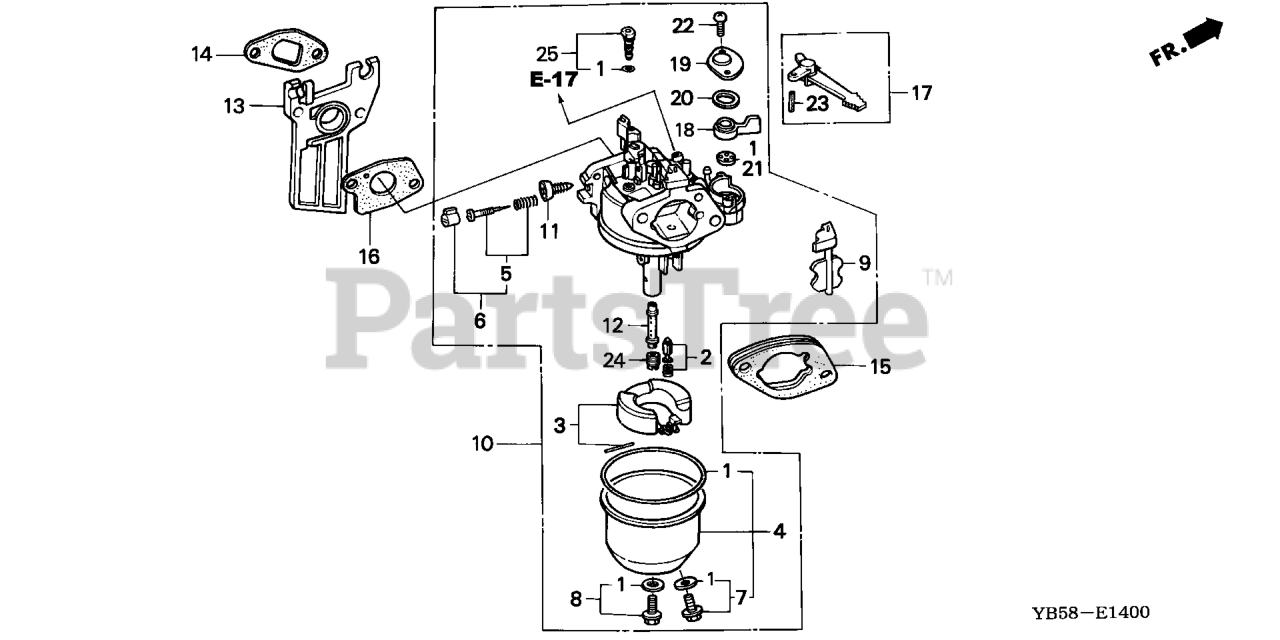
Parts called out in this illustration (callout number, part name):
1	GASKET SET (CARBURETOR NO.)
2	VALVE SET, FLOAT (CARBURETOR NO.) (SEAT NOT INCLUDED)
3	FLOAT SET
4	CHAMBER SET, FLOAT (CARBURETOR NO.)
6	SCREW SET (Honda Code 4219879). (CARBURETOR NO.)
7	SCREW SET, DRAIN (Honda Code 1672187). (CARBURETOR NO.)
8	SCREW SET B
8	SCREW SET
9	CHOKE SET
10	CARBURETOR ASSY. (BE61D B)
11	SCREW, THROTTLE STOP
12	NOZZLE, MAIN
13	INSULATOR, CARBURETOR
14	GASKET, INSULATOR
15	SPACER, CARBURETOR
16	GASKET, CARBURETOR
17	LEVER, CHOKE (STD)
18	LEVER, VALVE
19	PLATE, LEVER SETTING (CARBURETOR NO.)
20	SPRING, PETCOCK LEVER (CARBURETOR NO.)
21	GASKET, VALVE
22	SCREW, PAN (3X6)
23	PIN, SPRING (2X12)
24	JET, MAIN (#55) (CARBURETOR NO.)
24	JET, MAIN (#58) Use from Engine SN BE30B E.
24	JET, MAIN (#60)
24	JET, MAIN (#62)
25	JET SET, PILOT (#35)
